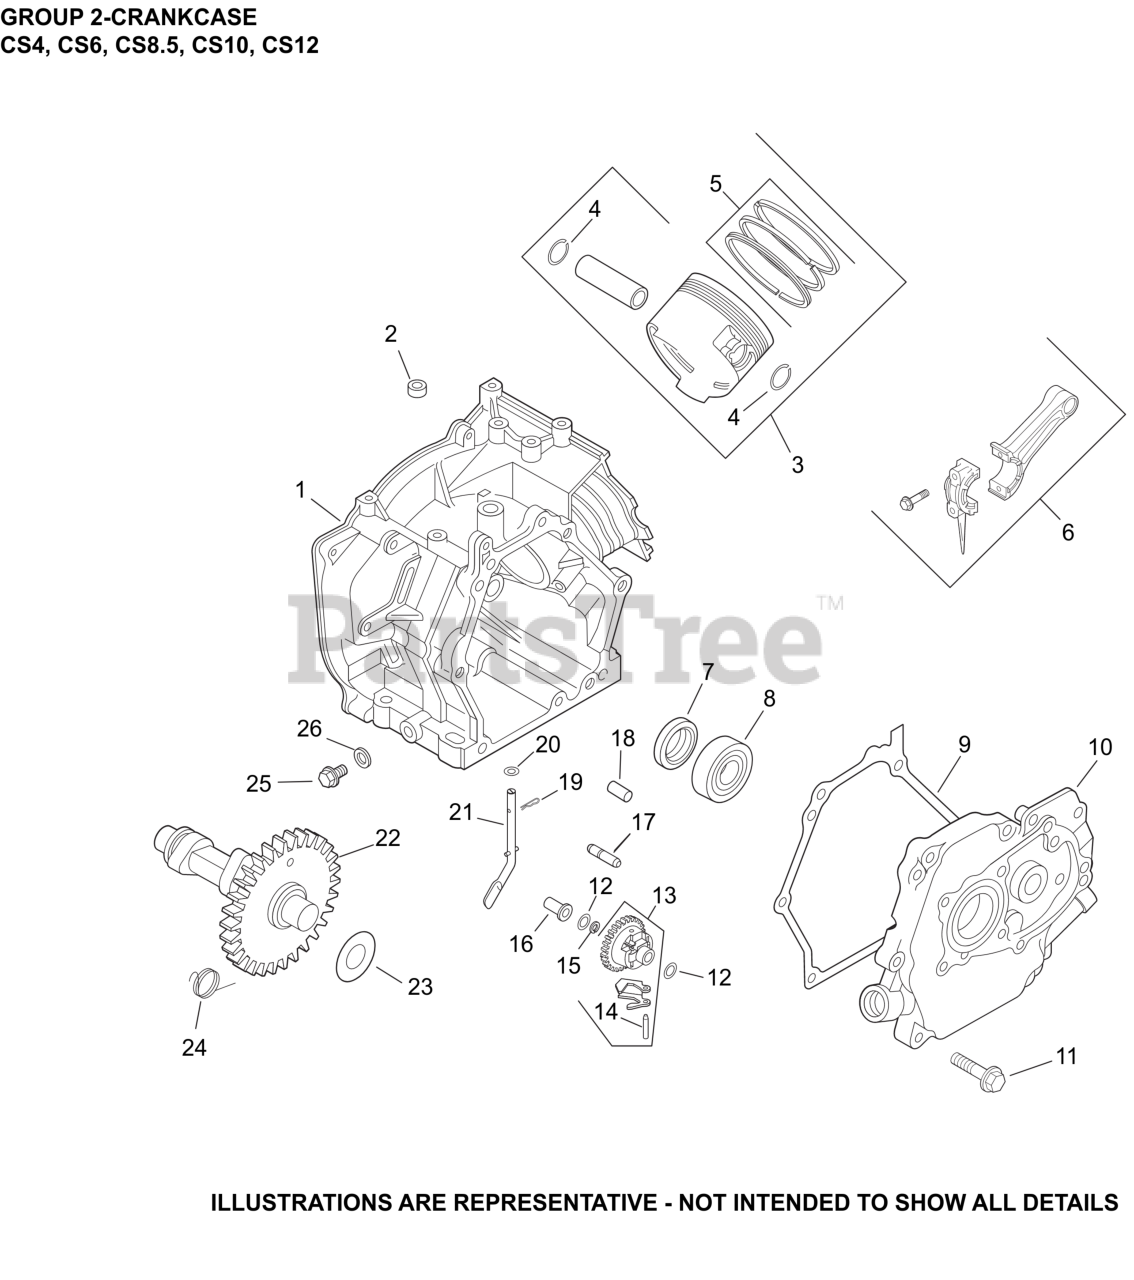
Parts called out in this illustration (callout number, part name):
2	SEAL, GOVERNOR CROSS SHAFT
3	PISTON W/RING SET (STD)
3	PISTON W/RING SET (+.25MM)-(#DSC)
3	PISTON W/RING SET (+.50MM)-(#DSC)
4	RING, RETAINER
5	STANDARD RING SET
5	0.25MM RING SET
6	CONNECTING ROD
7	SEAL, FRONT OIL
9	GASKET, C.P.
10	CLOSURE PLATE, G.R.
11	SCREW, FLANGE
13	GEAR, GOVERNOR -USE 63 043 07-S
13	GOVERNOR GEAR ASSEMBLY
14	PIN - USE APPL GOV GEAR ASSY
15	SNAP RING
17	SHAFT, FLYWEIGHT
18	DOWEL PIN
21	SHAFT, GOV CROSS
24	SPRING, ACR
25	PLUG, DRAIN
NI	RING SET, 0.50
NI	BOLT, CONN ROD
NI	NSS - USE APPLICABLE PISTON/RING SET
